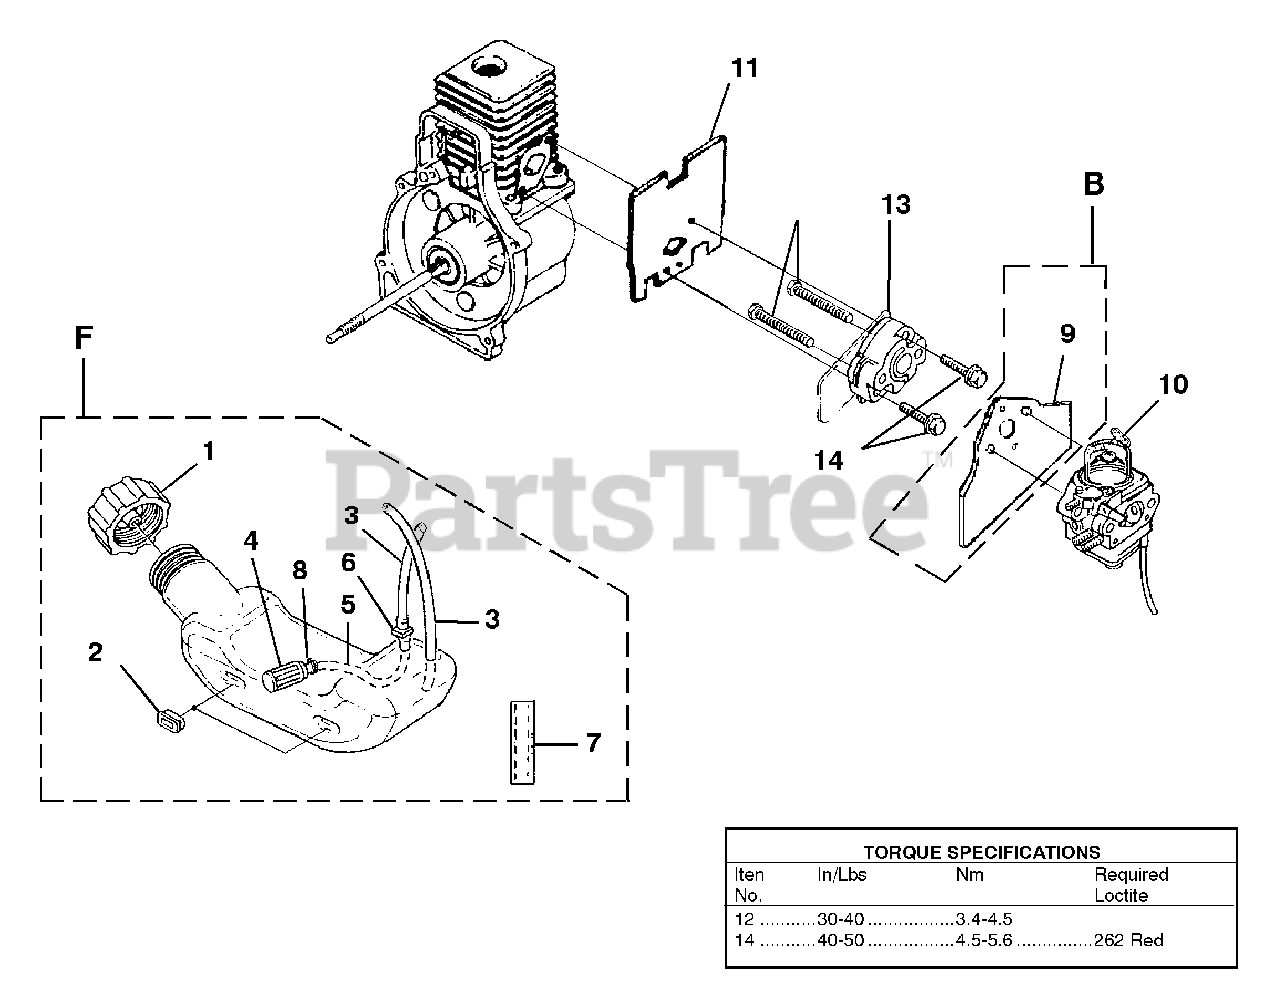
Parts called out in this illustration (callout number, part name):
1	FUEL CAP ( 1 5/8" Opening)
2	BUMPER-Rubber
3	TUBING-Rubber (5.5")
4	FUEL FILTER
5	TUBING-Rubber (6 1/4")
6	Fitting, Inlet
7	INSULATION-Tubing
8	CLAMP
9	GASKET-Carburetor
10	LEVER-Choke (Walbro WT419,WT469)
10	LEVER-Choke (Walbro WT471)
11	GASKET-Heat Dam
13	HEAT DAM
14	SCREW, SEMS (10-24 x 1.110)
F	FUEL TANK KIT
B	CARBURETOR KIT
B	CARBURETOR KIT (Bandit 2000, Yardbroom & D25B)
